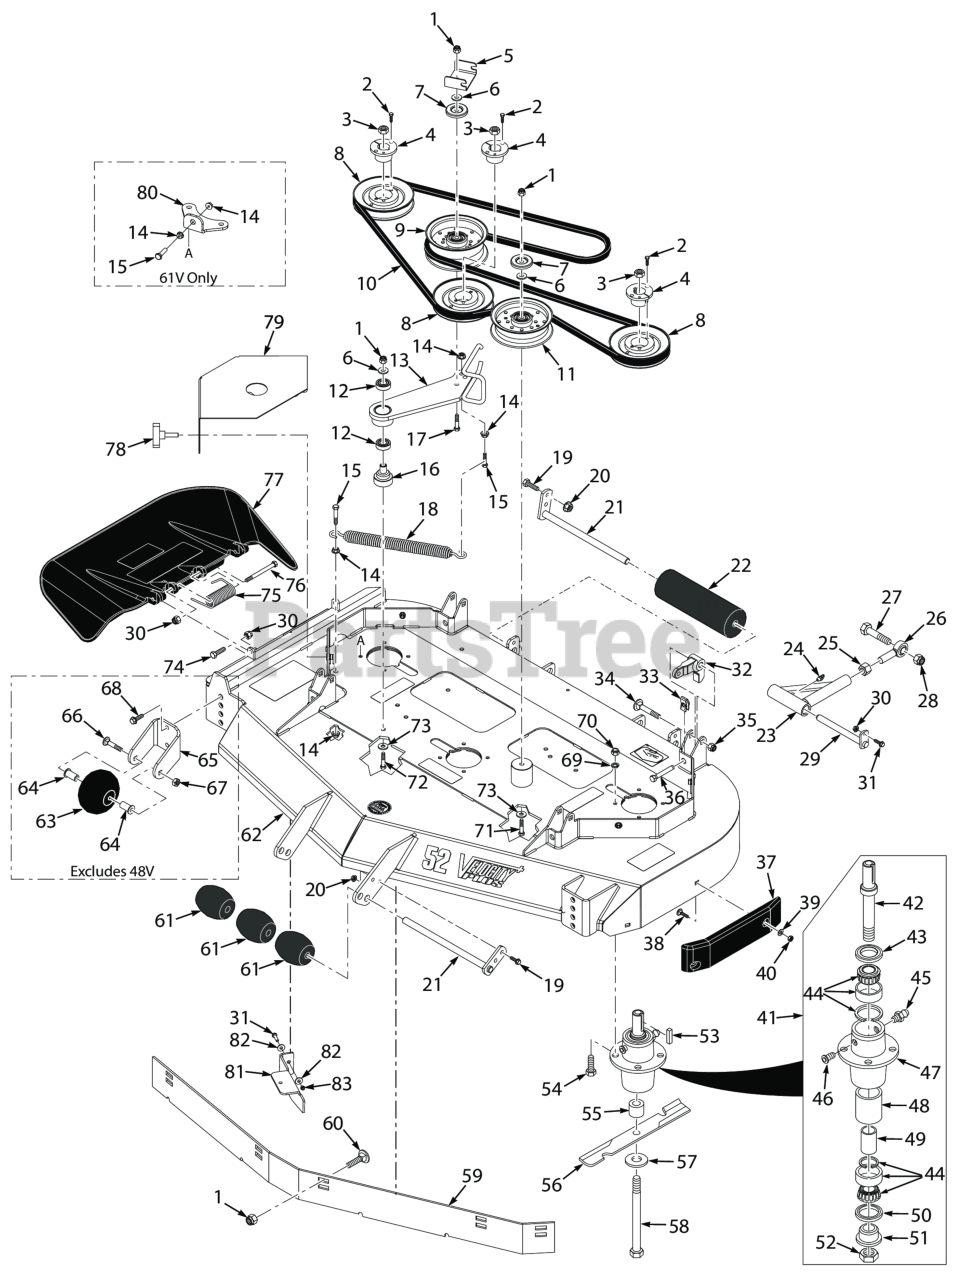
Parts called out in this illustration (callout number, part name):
1	HEX NUT, ELASTIC STOP LOCK, 3/8-16
2	Bolt, Hex Head 1/4-20 x 1" Grade 8 Black
3	Hex Locknut, Elastic Stop, 3/8-16
4	Hub, Tapered 1-1/8" Bore
5	Bracket, Belt Guide
6	Flatwasher, 3/8 (.391 x .938 x .105 HD) Grade 8
7	Quick Pin, 5/16" Dia.
8	Pulley, Tapered Bore 6.33" Dia.
9	Pulley, Idler 5" Dia.
10	Belt, Cutter Deck - 61V
11	Idler Pulley, Belt Clutch
12	BEARINGS, BALL, NEUTRAL RETURN
13	Idler Arm Assy. - 61V
14	NUT, 3/8-16 SERRATED FLANGE HEX HEAD
15	Bolt, Hex Head 3/8-16 x 1-1/2" Grade 8 Black
16	Pivot, Idler - Short
17	Capscrew, Hex Head 3/8-16 x 3.25"
18	Spring, Cutter Deck
19	Bolt, Heax Head 5/16-18 x 1" (48V / 52V)
20	Nut, Flange Head Elastic Stop 5/16-18
21	Shaft Weldment, Guide Roller
22	Guide Roller
23	Pusharm Assembly, LH
23	Pusharm Assemblly, RH
24	Grease Fitting, 90 Degree
25	Nut, Hex Head 5/8-18 UNF
26	Rod End, 5/8" Male RH Thread
27	BOLT, HEX HEAD 5/8-11 X 4-1/2"
28	HEX LOCKNUT, ELASTIC STOP, 5/8-11
29	Shaft Weldment, Pusharm Mounting
30	HEX NUT, ELASTIC STOP LOCK, 5/16-18
31	Bolt, Heax Head 5/16-18 x 1" (48V / 52V)
32	Lever, Deck Level
33	U-Nut, 3/8-16 (short)
34	Bolt, Carriage 7/16-14 x 2-1/4"
35	HEX LOCKNUT, ELASTIC STOP, 7/16-14
36	Bolt, Hex Head 3/8-16 x 2-1/2" Soecial Lock
37	Pad, Deck Wear
38	Bolt, 5/16-18 x .75 RHSN Carriage
39	Flatwasher, 5/16-.344 x .688 x .065 (48V / 52V)
40	Nut, Center Lock, 5/16-18(32)
41	Cutter Spindle Assembly
42	Spindle Shaft, Tapered Brng
43	SEAL, 2.00 O.D. X 1.50 BORE
44	Tapered Bearing Set (Two Bearings W/Race)
45	GREASE FITTING, STR. 1/4-28 SELF TAP.
46	RELIEF FITTING, TAPERED BEARING SPINDLE
47	Housing, Spindle
48	Spacer, Outside, Cutter Spindle
49	SLEEVE, CUTTER SPINDLE
50	Seal, 2.00" O.D. x 1.625" Bore
51	SPINDLE BUSHING, BOTTOM
52	Nut , Spec ial 1 -1/ 1 6 - 1 8
53	Key, 1/4 x 1/4 x 2.0"
54	Bolt, Hex Head 5/16-18 x 1-3/4" Grade 8
55	Spacer, Spindle Bottom
56	Cutter Blade, 21" (35BV & 37BV-EFI)
57	Flatwasher, 5/8-.688 x 1-3/4 x .134 HD
58	BOLT, HEX HEAD, 5/8-11 X 9-1/2 GR.5
59	Baffle Custom-Cut, 61V (7-Position)
60	Carriage Bolt, 3/8-16 x 1.0"
61	Wheel, Anti-Scalp
62	Cutter Deck w/Decals - 61V
63	Bolt, Carriage 3/8-16 x 4"
64	Bushing, .376" I.D. Oilite
65	Bracket, Anti-Scalp Wheel
66	Bolt, Hex Head 3/8-16 x 3-1/2"
67	Bolt, Hex Head 3/8-16 x 1" Ser. Flg.
68	Capscrew, 3/8-16 x 1.0" Serrated Flange Hex Hd
69	Lockwasher, 5/16 (.317 x .586 x .078) Helical Spring
70	Lock Nut, 5/16-18 Elastic Stop Grade 8
71	Bolt, 3/8-16 x 5.00" Hex Head
72	Capscrew, Hex Head 3/8-16 x 3.25"
73	Flatwasher, 3/8-.406 x 2.25" x .1875
74	Bolt, Hex Head 5/16-18 x 1-1/2" - Front
75	Spring, Discharge Chute
76	Bolt, 5/16-18 x 4-3/4" Hex Head
77	Discharge Chute Advantage - Large
78	Knob, w/stud 3/8-16 x 1-1/4"
79	Belt Cover, RH - 61V
79	Belt Cover, LH - 61V
80	Anchor Bracket - 61V
81	Turbo Baffle, Bolt On
82	Flatwasher, 5/16-.375 x .875 x .083 (35BV & 37BV-EFI)
83	HEX NUT, ELASTIC STOP LOCK, 5/16-18
